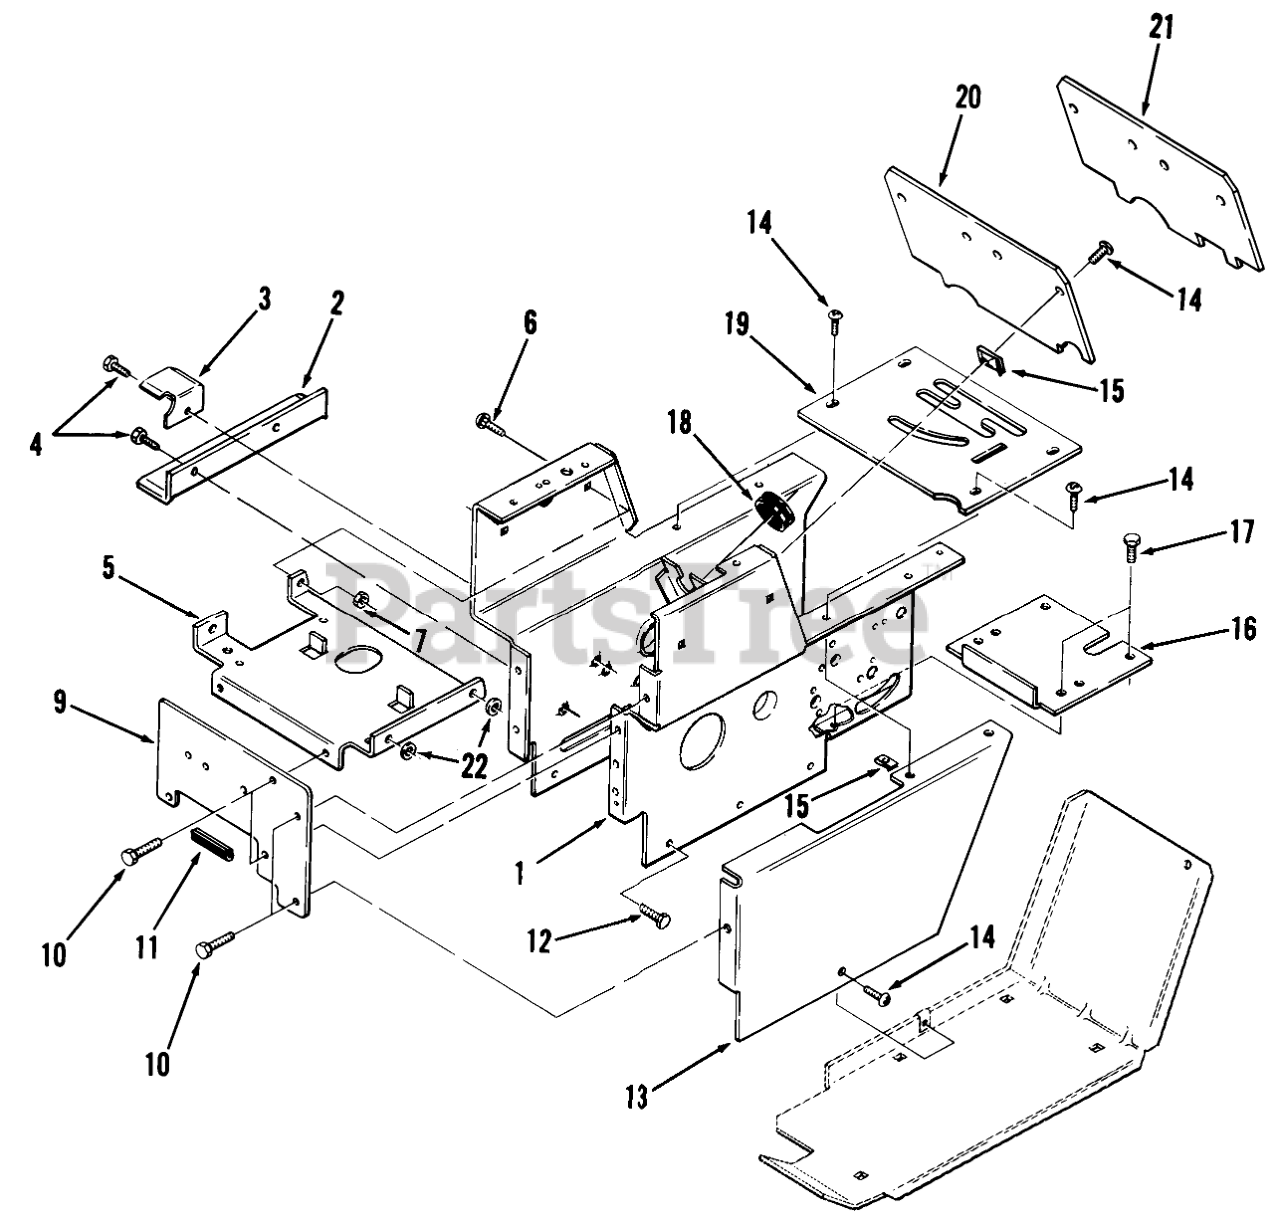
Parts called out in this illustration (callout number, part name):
1	Hoodstand
2	ANGL-BLT GURDB
3	BRCKET-BLT SUTB
3	Belt Bracket
4	SCREW
5	Battery Support Bracket
6	CARRIAGE BOLT -4
7	Nut
9	Front Plate
9	Front Plate C-161 Twin Only
10	SCREW
11	EDGE TRIM 2" 102896
12	SCREW
13	Side Cover LH
14	Screw
16	Cover-Dust
17	SCREW
18	GROMMET
19	Shift Cover Plate
19	PLATE-SHIFT PATTE B
20	PLATE-HOODSTAND REAR
21	Hood Stand Plate
22	WASHER 5/16 SAE
